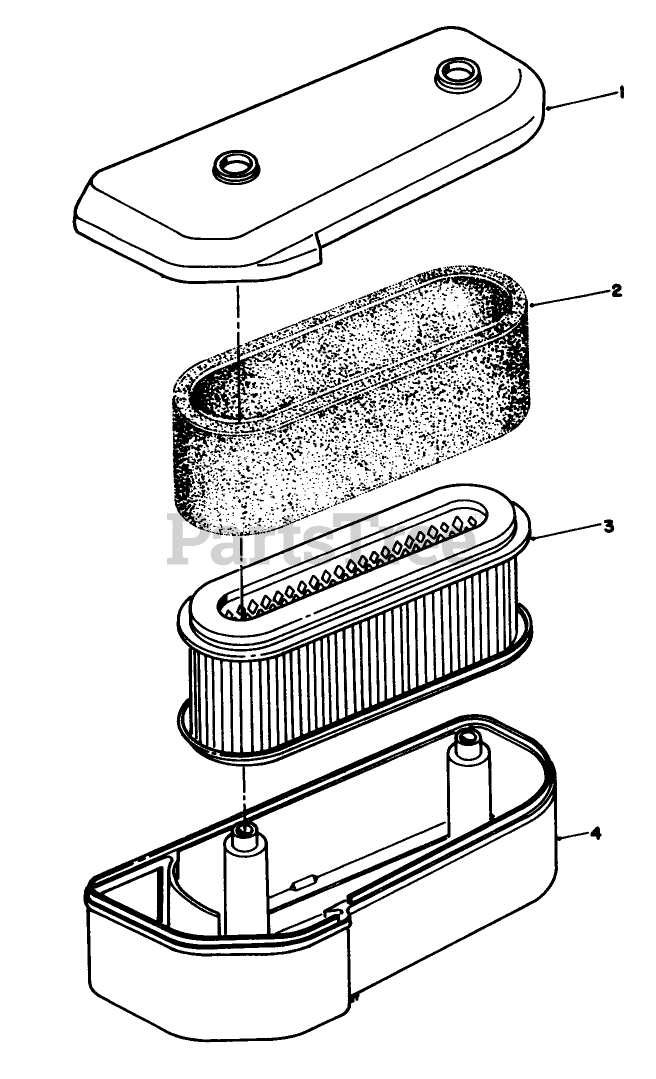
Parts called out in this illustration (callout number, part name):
1	CAP-Air Filter
2	Element
3	Element
4	CASE-Air Filter
